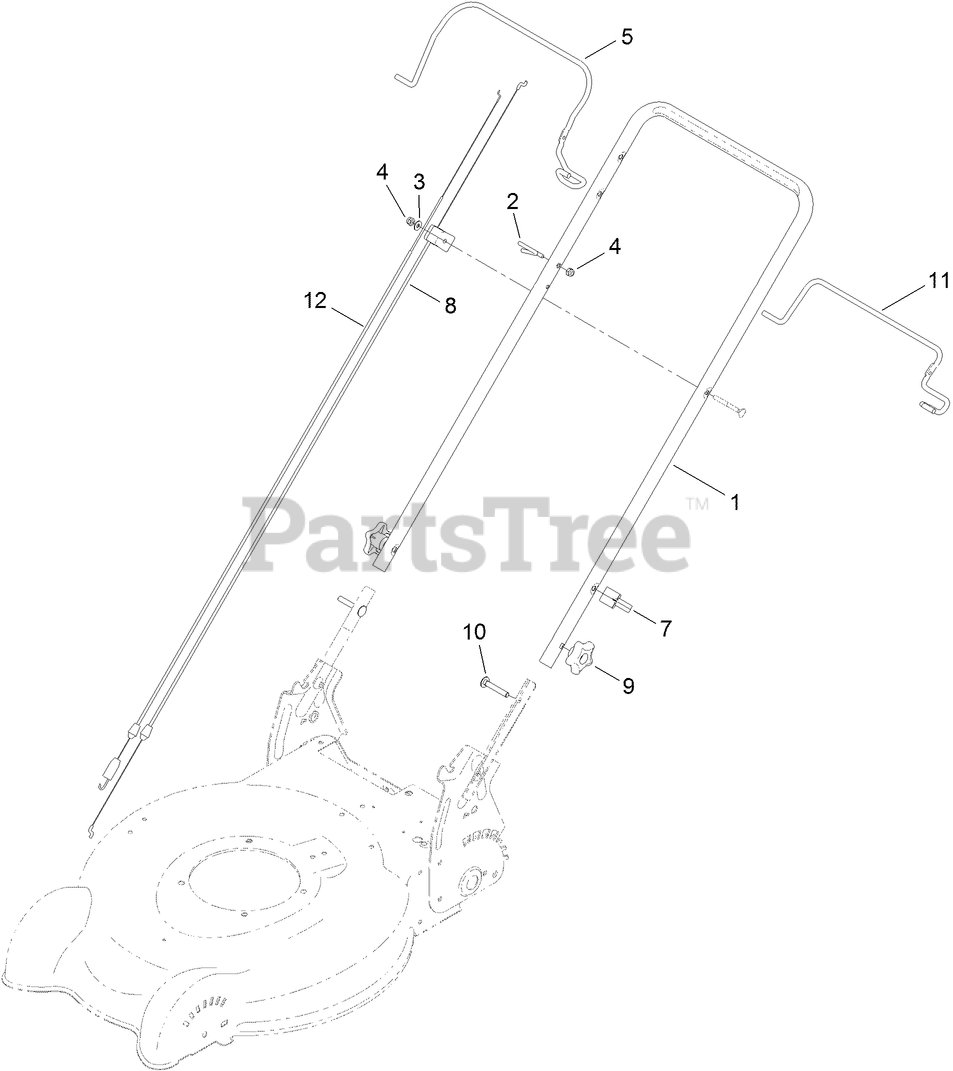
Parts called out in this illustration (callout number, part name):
1	HANDLE-UPPER
2	GUIDE-ROPE
3	WASHER-FLAT
4	NUT-LOCK, NI
7	GUIDE-CABLE
8	CABLE-BRAKE
9	KNOB-HANDLE
10	BOLT-CARR
11	BAIL-TRACTION, 2-BAIL FLAT
12	CABLE-TRACTION
